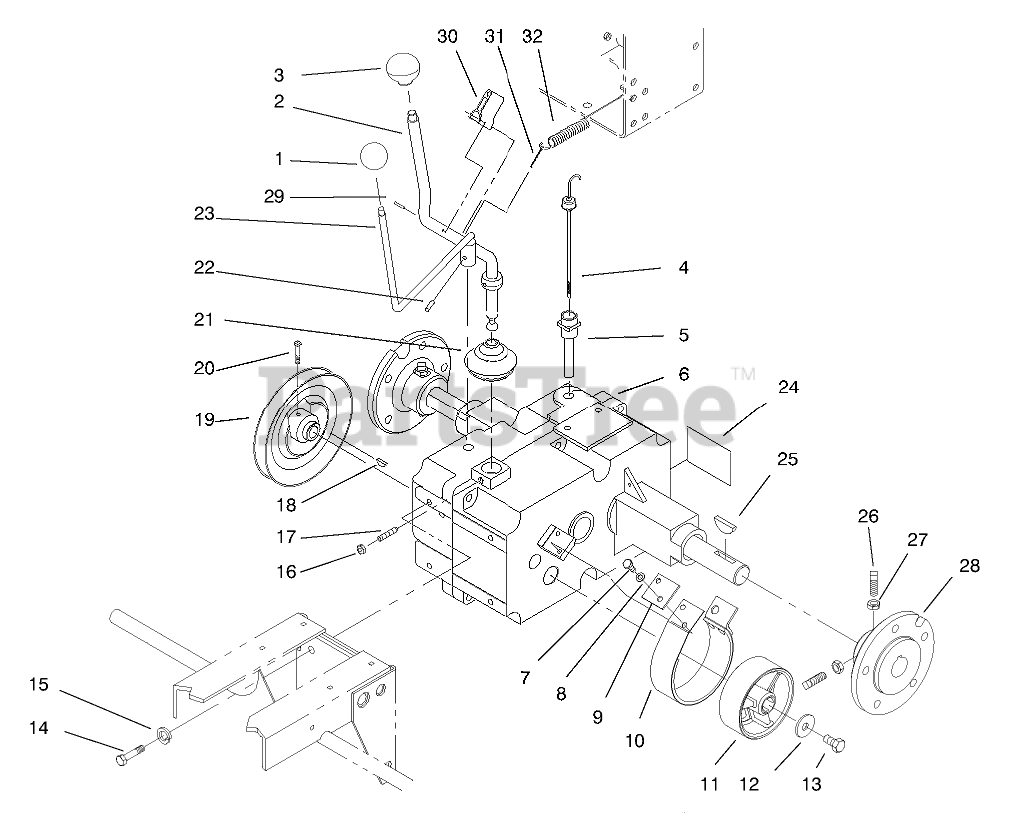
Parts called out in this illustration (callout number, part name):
2	SHIFT ROD ASM
4	DIPSTICK
5	NIPPLE-FILL, TRANSMISSION
6	TRANSMISSION ASM 8 SPD 4
7	SCREW-HH
8	WASHER-LOCK
9	PLATE-BRAKE
10	BRAKE BAND ASM
11	DRUM-BRAKE
12	WASHER
13	SCREW-HEX HD CAP
14	SCREW-HH
15	WASHER-LOCK
16	NUT-HEX
17	SETSCREW
18	KEY-HI PRO
19	PULLEY-TRANSMISSION
20	SCREW-SQH
21	COVER-DUST
22	PIN-SPIROL
23	SHIFT ROD ASM
24	DECAL-UNIDRIVE
25	KEY-WOODRUFF
26	SCREW-SET, SQH
27	NUT-JAM
28	HUB-WHEEL
30	MAGNET CLIP ASM
31	PIN-COTTER
32	SPRING-EXTENSION
